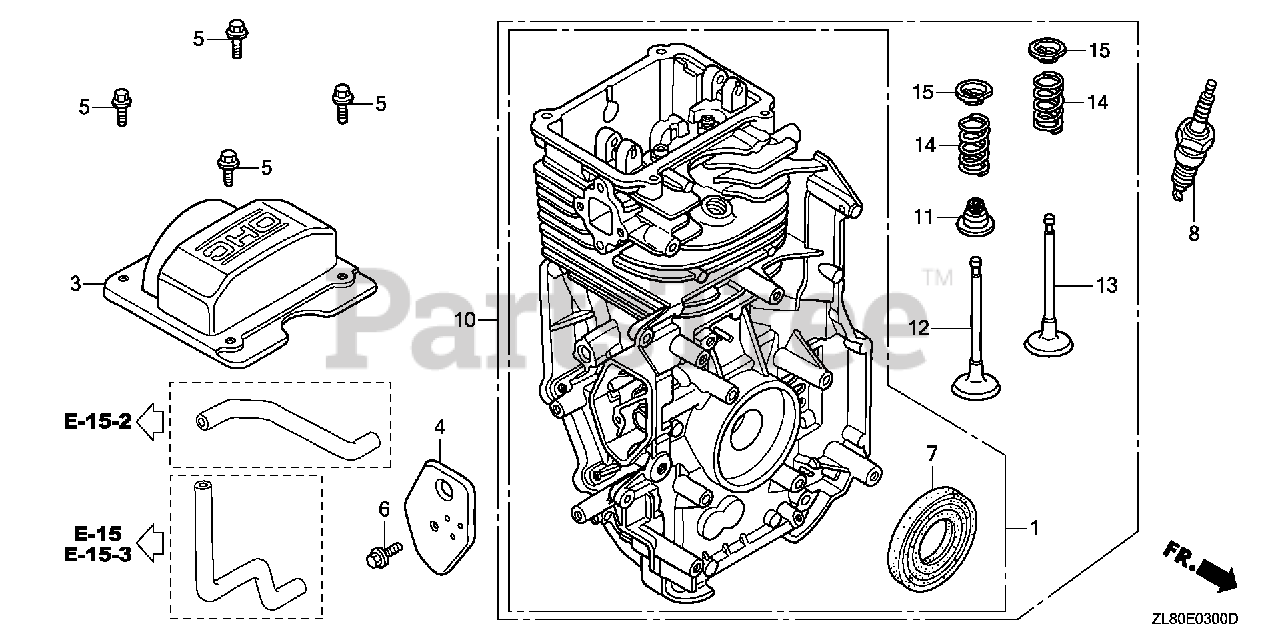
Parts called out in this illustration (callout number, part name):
1	CYLINDER ASSY.
3	COVER, CYLINDER HEAD
4	COVER, BREATHER (Honda Code 5580006). (BREATHER VALVE ASSY.)
5	BOLT, FLANGE (6X12) (CT200)
6	BOLT, FLANGE (6X14)
7	OIL SEAL (25.4X62X6)
8	SPARK PLUG (BPR6ES) (NGK)
11	SEAL, VALVE STEM
12	VALVE, IN. (TECHNOSTAR)
12	VALVE, IN.
13	VALVE, EX. (L8E)
13	VALVE, EX. (C8E)
14	SPRING, VALVE
15	RETAINER, VALVE SPRING
